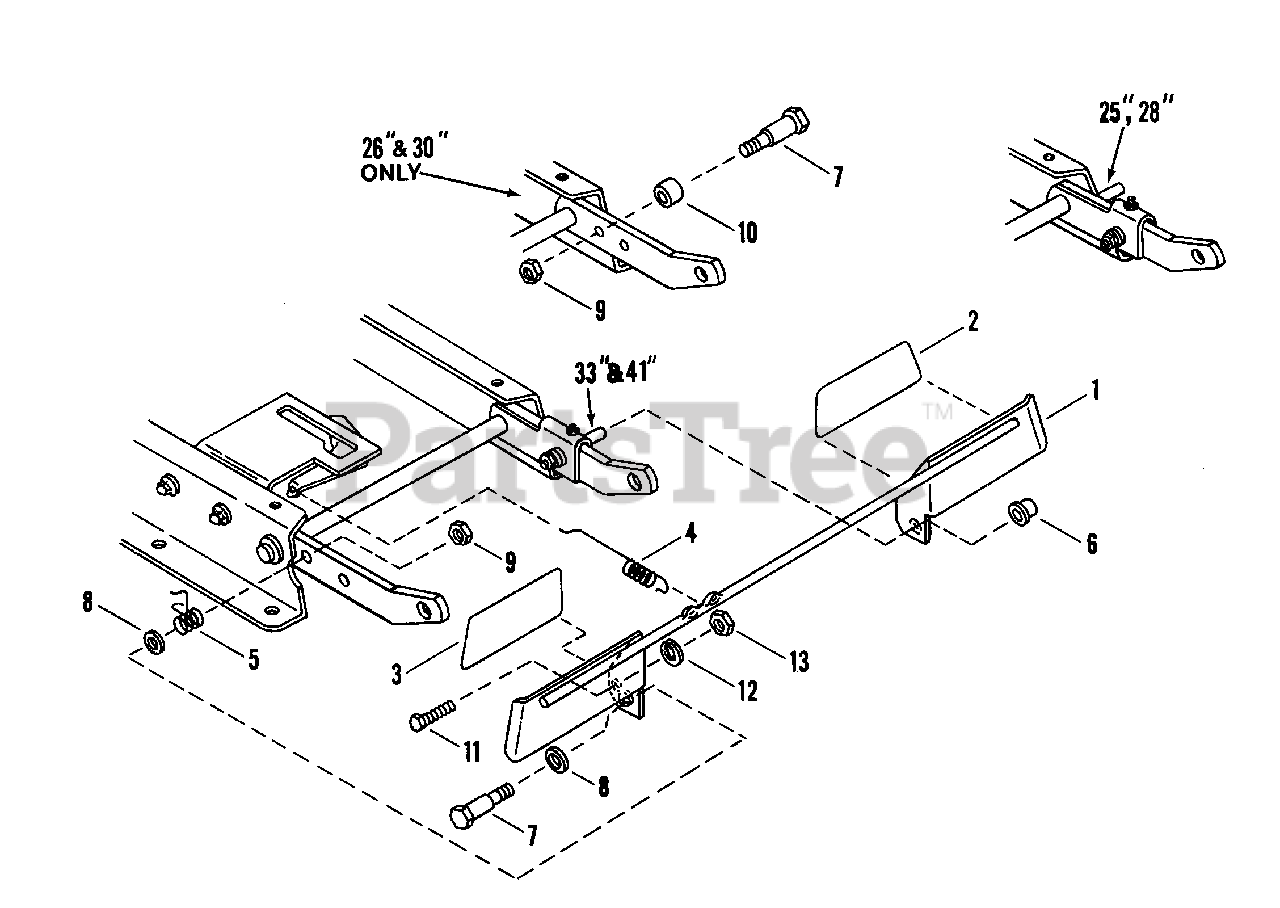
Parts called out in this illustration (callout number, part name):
1	PEDAL, Blade Stop Control
2	* PAD, Left Hand Pedal Tread (NLA)
3	* PAD, Right Hand Pedal Tread (NLA)
4	SPRING, Latching 4.24" Long
4	SPRING, Latching 5.58" Long
5	SPRING, Pedal
6	PUSH-NUT, 1/2"
7	BOLT, 3/8-24x1-3/4 Shoulder
8	WASHER, 1/2 SAE
9	NUT, 3/8-24 Hex
10	SPACER
11	SCREW, 1/4-28x1" Hex Head Cap
12	LOCKWASHER, 1/4 Internal Tooth
13	NUT, 1/4-28 Hex
